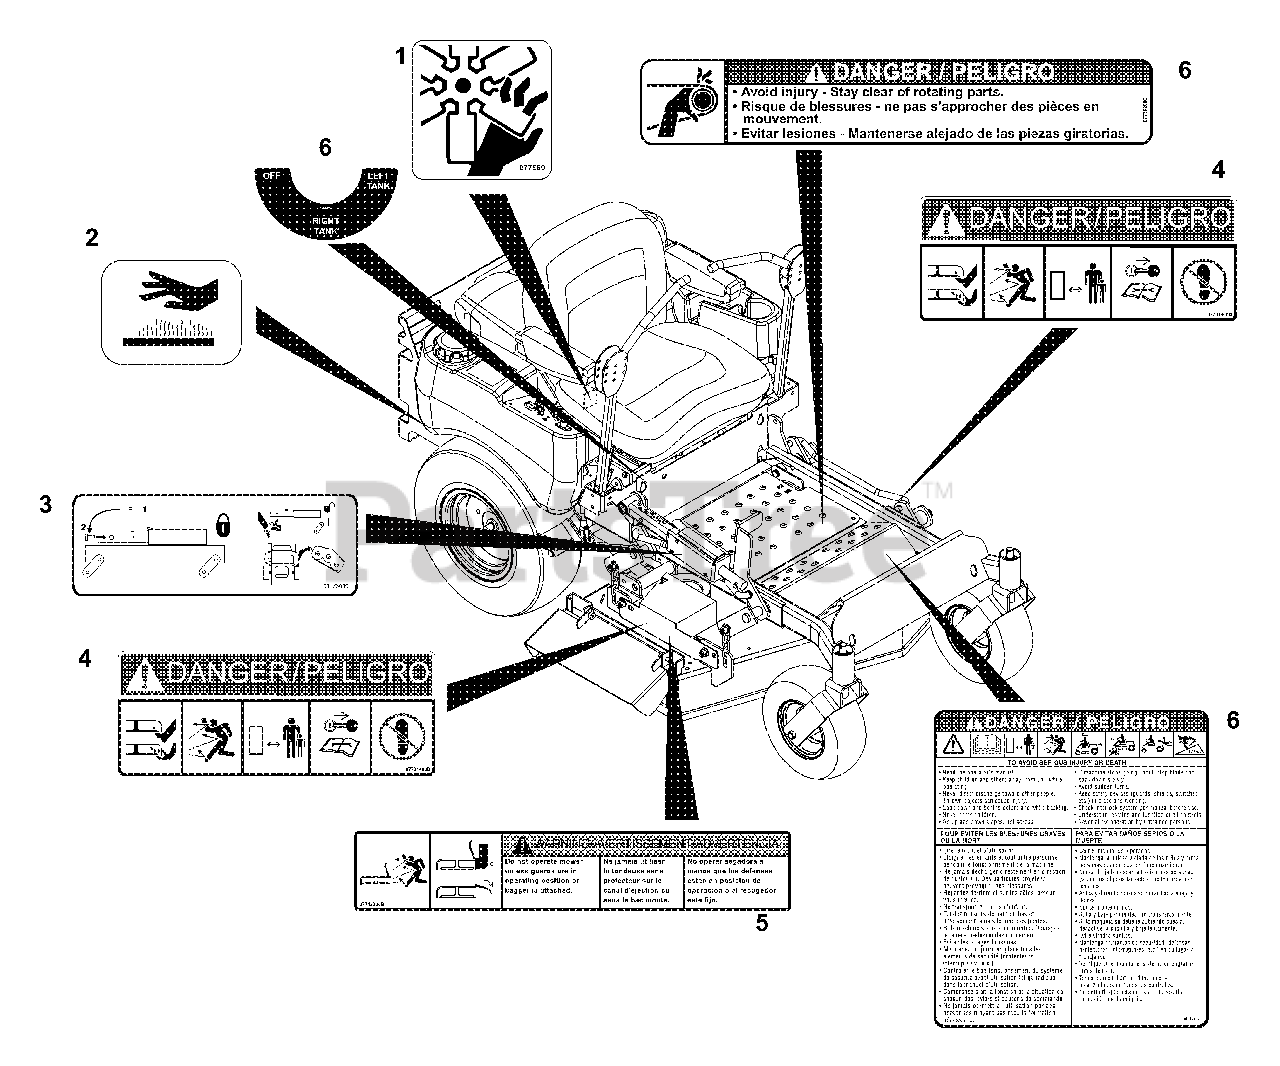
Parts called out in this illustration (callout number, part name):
1	DECAL, DANGER FAN
2	DECAL, HOT SURFACE
3	DECAL, DECK SERVICE
4	DECAL, MOWER PAN DANGER
5	DECAL, WARNING
6	SET-DECAL, COMMON DANGER/FUEL
